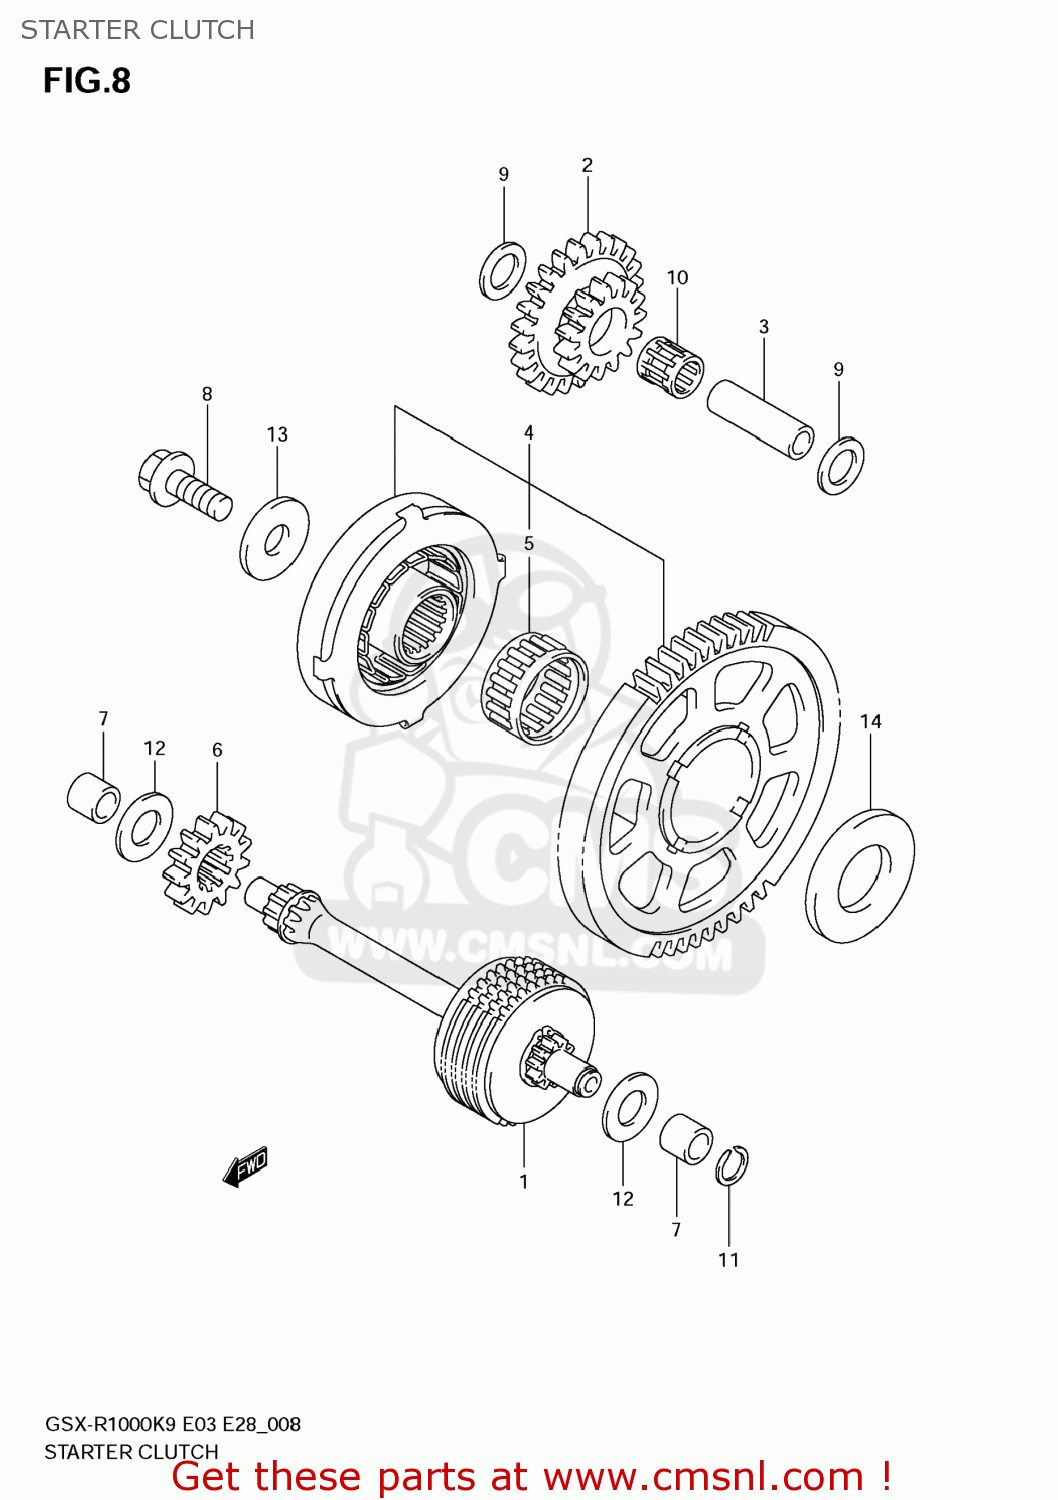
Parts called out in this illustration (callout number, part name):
1	LIMITER,START
2	GEAR,STARTER IDLE NO.2
3	PIN,PISTON
4	CLUTCH SET,STARTER
5	BEARING(26X31X16)
6	GEAR,LIMITER DRIVEN
7	BUSH,LIMITER GEAR SHAFT
8	BOLT(10X23)
9	SHIM(12X20X1)
10	BEARING(12X16X16)
11	CIRCLIP
12	WASHER
13	WASHER
14	WASHER
